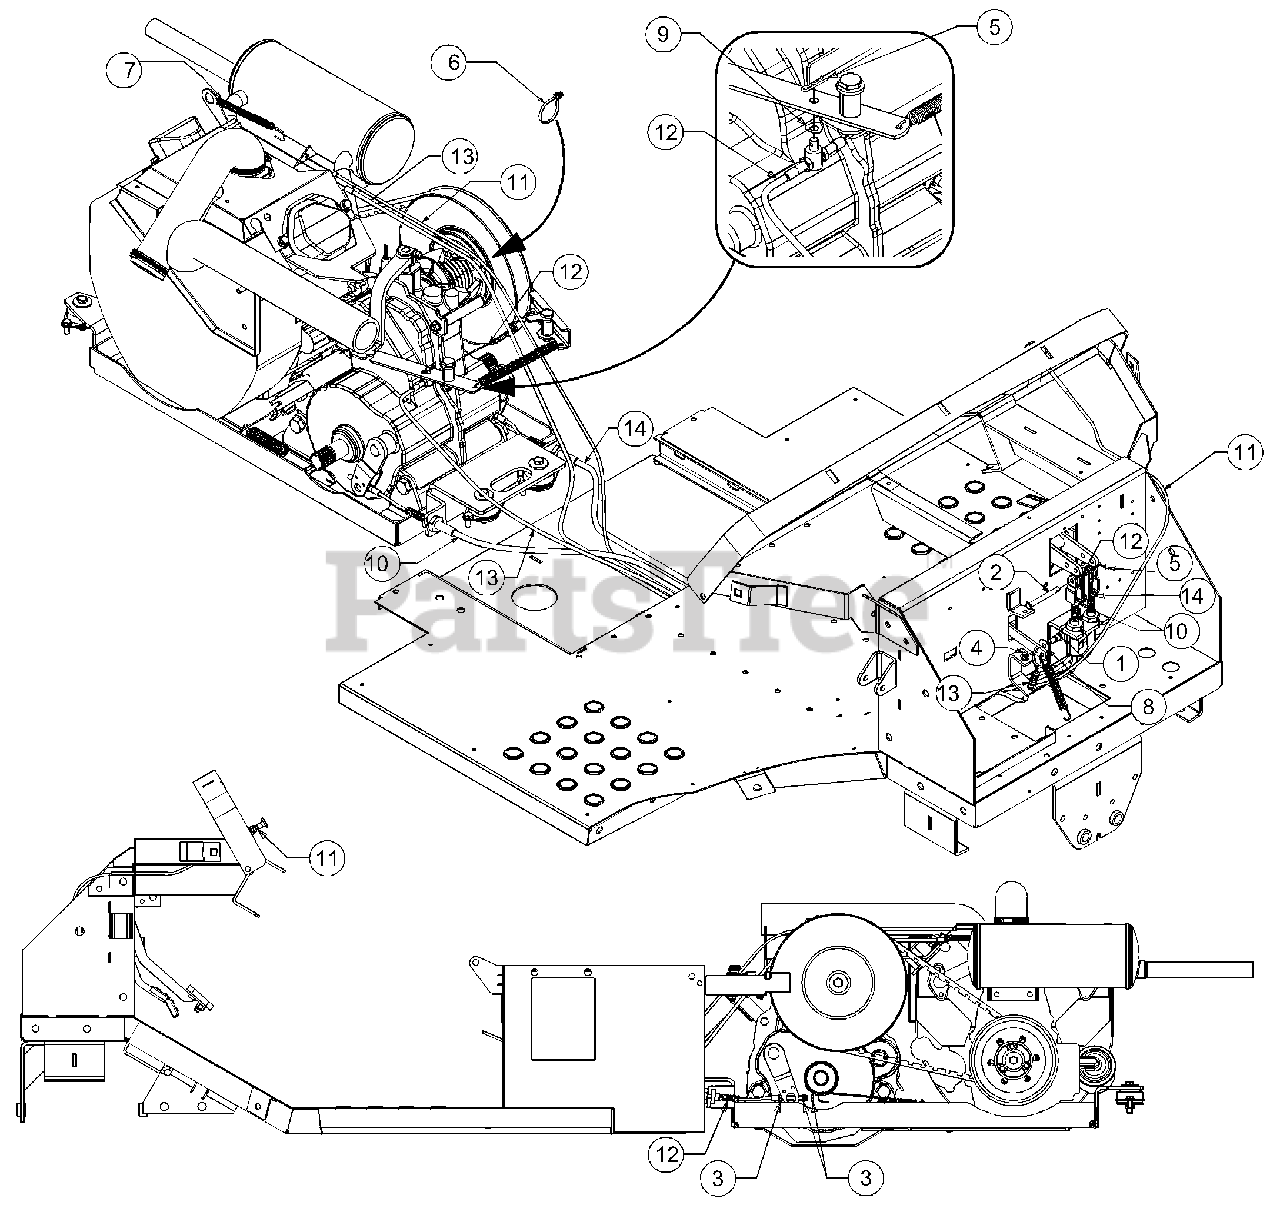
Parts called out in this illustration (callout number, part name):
1	Screw, Shoulder, .375 x .375
2	Pin, Clevis, 5/16 x 2.5
3	Nut, Jam, 5/16-24, Gr5
4	Nut, Hex Lock, 5/16-18
5	Pin, Cotter, .072 x 1.13
6	Cable Tie, Tree Mount
7	Extension Spring
8	Washer, .349 x .879 x .063
9	Washer, Spring, .317 x .879 x .063
10	Cable, Control, Brake
11	Cable, Control, Choke
12	Cable, Control, Clutch Brake
13	Cable, Control, Throttle
14	Cable, Control, Brake
